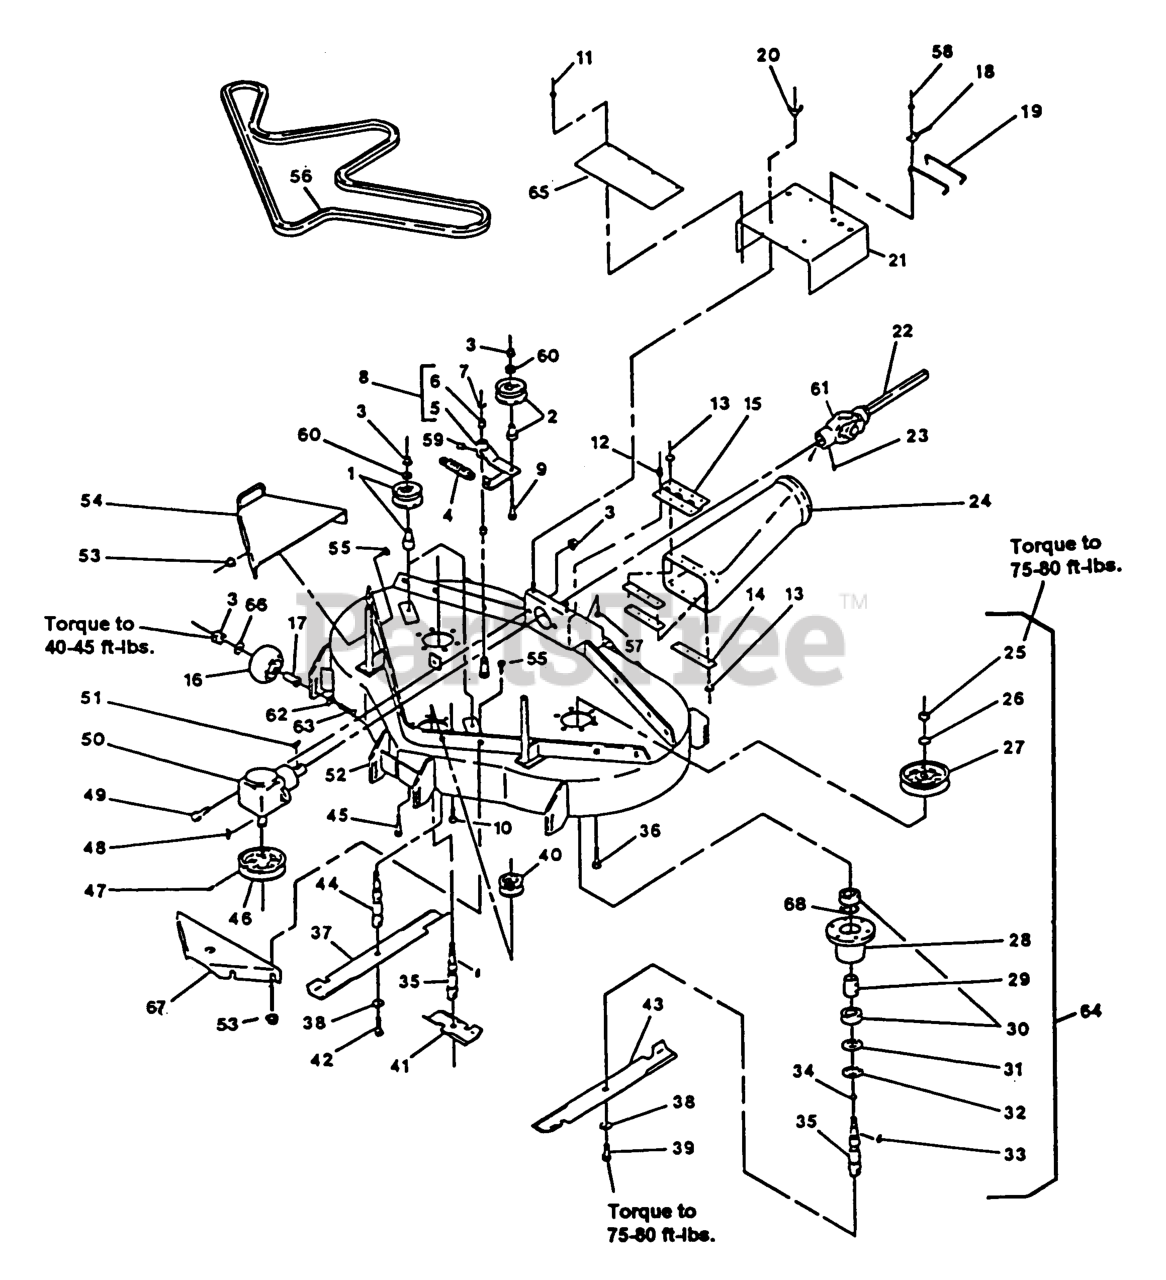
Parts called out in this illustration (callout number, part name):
1	KIT,IDLER & BUSHING
4	SPRING-IDLER, DECK
6	SLEEVE-BEARING
11	RIVET-POP
16	ROLLER-SCALP, ANTI
17	BUSHING-ROLLER
18	CLIP-DECK, HOLD UP ROD
20	WINGNUT-NYLOCK
22	PTO SHAFT,SHAFT HALF PNT
26	WASHER-SPRING
28	HOUSING,BEARING
29	SPACER,BEARING
30	BEARING,HD SPINDLE
31	SEAL,MECHANICAL DUST
32	RING,SNAP WLDS N5000-244
36	SCRW,TPTTE HH
38	WASHER-SPRING
44	SPINDLE,BLADE RH
47	SCREW-SET
50	GEARBOX, PEERLESS
54	WLD,GUARD BELT
57	BOLT-CARR
58	Rivet, 3/16 X 1/4
65	SHIELD,PTO GUARD
